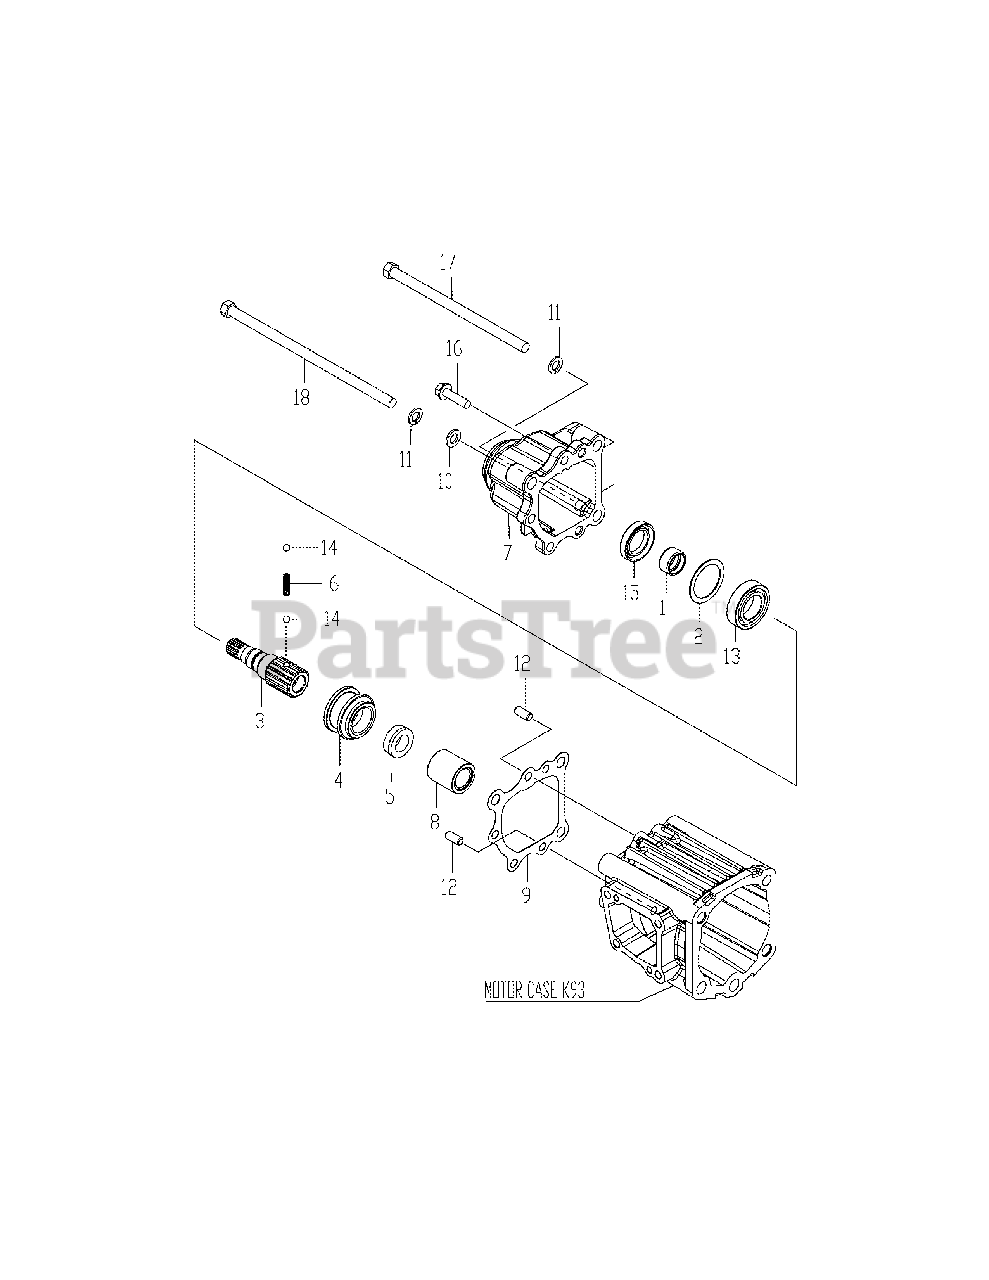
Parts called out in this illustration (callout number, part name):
1	Sleeve, Si20X25X13
2	Washer, 36X46X1
3	Shaft, Front Drive
4	Collar, Front Shift
5	Collar, Front Spline
8	Spacer, 20X33X285
9	Packing, Front Cover
13	Bearing, 6005 Ntn
15	Seal, Tc254008
17	Bolt, 10 X 180
18	Bolt, 10 X 220
